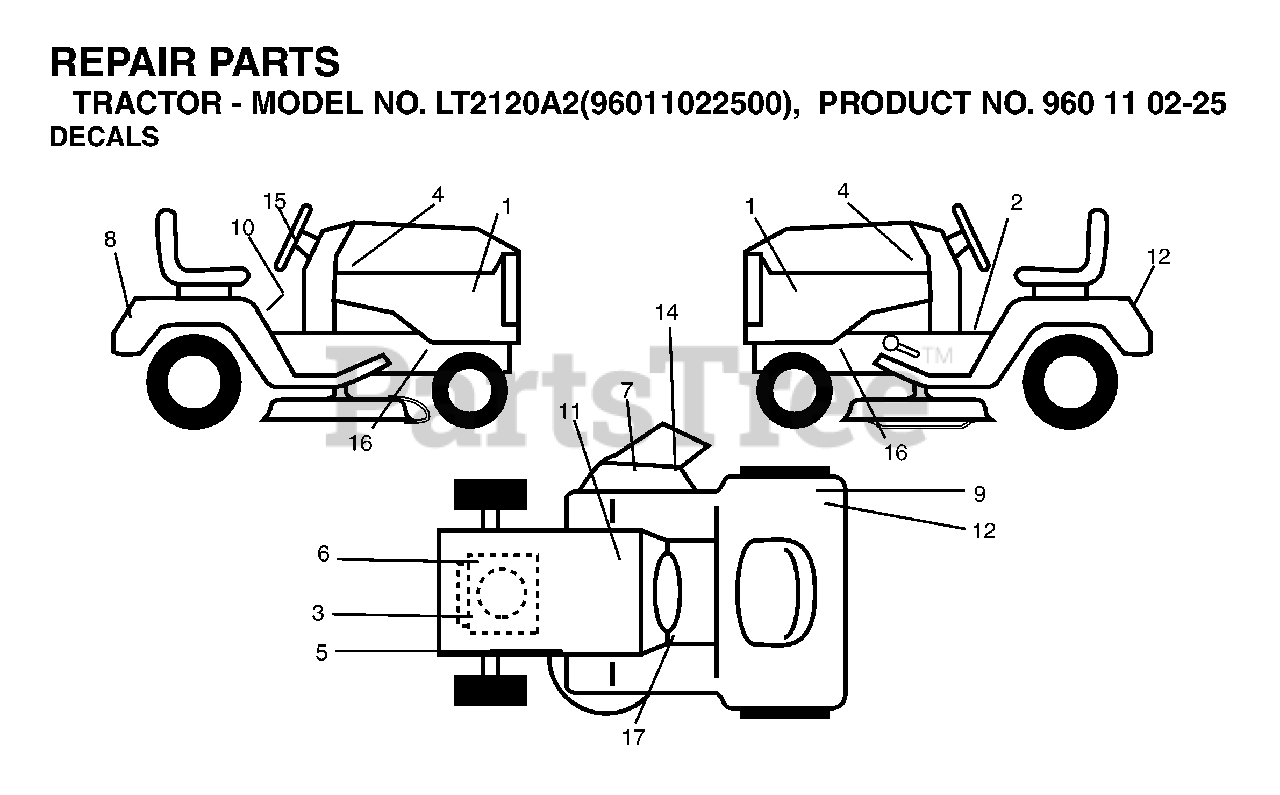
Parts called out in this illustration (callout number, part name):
2	DECAL PARK BRAKE
5	DECAL V BELT SCHEMATIC
7	DECAL.INTERNATIONL.CUTFINGER
9	DECAL.80 DBA.AUSTRALIA
11	DECAL BTRY SYMBOLS
14	DECAL, DEFLECT WARNING
